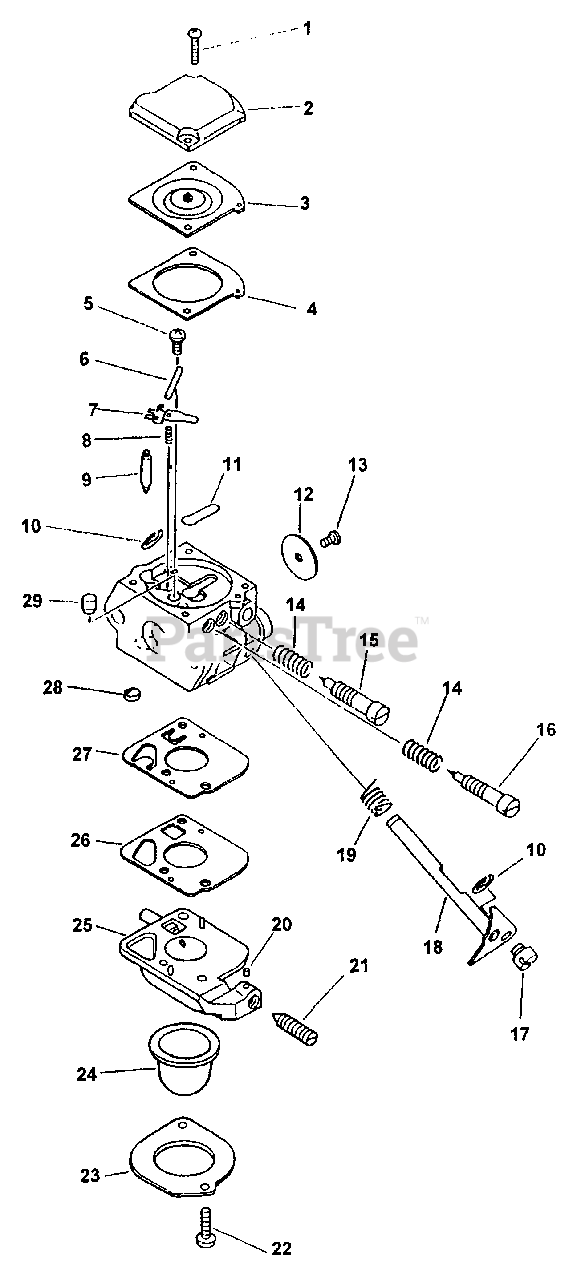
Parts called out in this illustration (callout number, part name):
2	COVER, METERING
3	DIAPHRAGM, METERING
4	GASKET, METERING
5	SCREW, METERING LEVER PIN
6	PIN, METERING LEVER
7	LEVER, METERING
8	SPRING, METERING LEVER
9	VALVE, INLET NEEDLE
10	RING, RETAINING
11	PLUG, WELCH
12	VALVE, THROTTLE
15	NEEDLE - MIXTURE
16	NEEDLE - HIGH SPEED
18	SHAFT, THROTTLE
19	SPRING, RETURN
20	PIECE, FRICTION
21	SCREW, IDLE ADJUST
22	SCREW, RETAINER
23	RETAINER, PURGE BULB
24	BULB, PURGE
25	BASE, PURGE
26	GASKET, PURGE
27	DIAPHRAGM, PURGE
28	STRAINER
29	NOZZLE, CHECK VALVE
